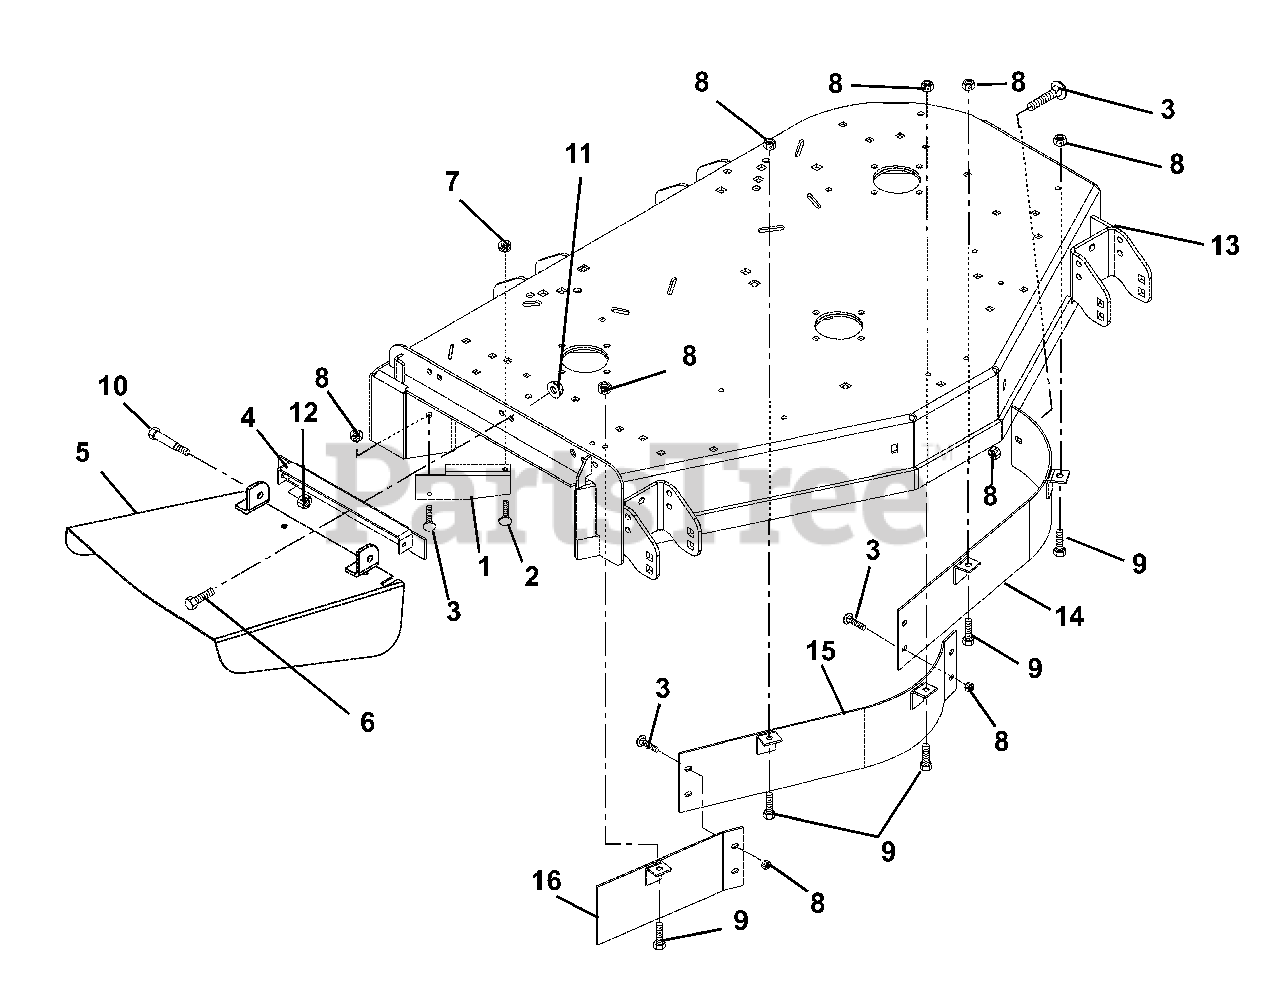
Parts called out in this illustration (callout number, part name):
1	Deflector- 60" (073, 075, 318, 319)
1	Deflector- 72" (074, 076)
2	Bolt-Round Head Square Neck .38-16 x .75 Grade 5
3	Bolt-Round Head Square Neck .31-18 x .75 Grade 5
4	Weldment, Discharge Chute Bracket
5	Chute-Discharge (073, 075, 318, 319)
5	Chute-Discharge (074, 076)
6	Bolt-Hex .38-16 x 1.00 Grade 5
7	Nut-Locking-Top-Flange .38-16
8	Nut, Locking-Top-Flange .31-18
9	Bolt, Hex .31-18 x .75 Grade 5
10	Bolt, Shoulder .38-16 x .50 Socket Head
11	Nut, Flange .375-16
12	Nut, Locking-Center .38-16
13	Weldment, 60" Mower Deck (073, 075, 318, 319)
13	Weldment, 72" Mower Deck- Float (074, 076)
14	Weldment, Upper Baffle Left 60" (073, 075, 318, 319)
14	Weldment, Baffle, Left Front-72" (074, 076)
15	Weldment, Baffle, Center Front 60" (073, 075, 318, 319)
15	Weldment, Baffle, Center Front 72" (074, 076)
16	Weldment, Baffle, Right Front 60" (073, 075, 318, 319)
16	Weldment, Baffle, Right Front 72" (074, 076)
